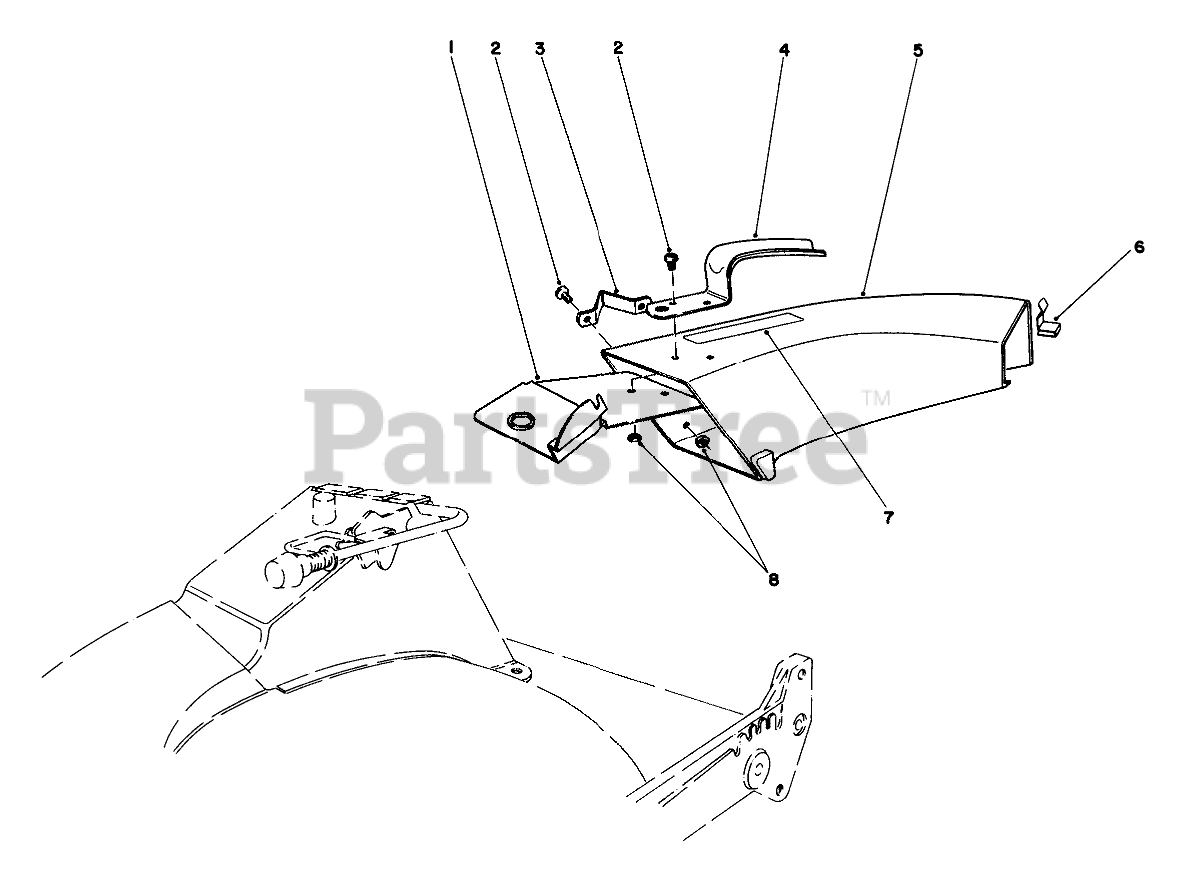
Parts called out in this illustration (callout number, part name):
1	Plate-Discharge Chut
2	10-24 X 5/8 PAN HD MS
3	SIDE BRACKET
4	CHUTE HANDLE
5	Chute Assembly (Incl. Ref. #1-6)
6	Clip
7	DECAL CAUTION
8	NUT-LOCK, NI
